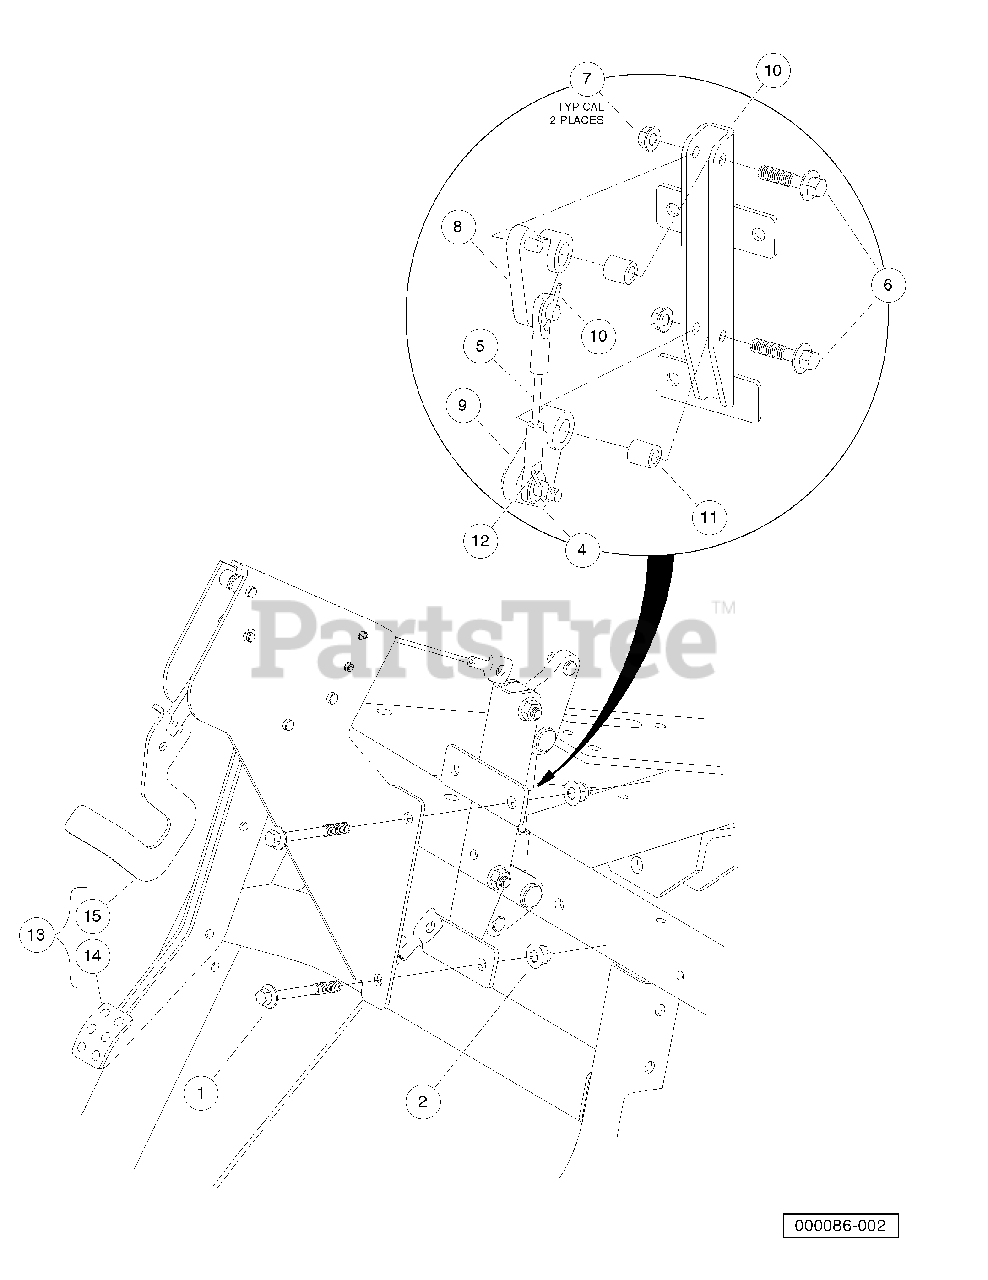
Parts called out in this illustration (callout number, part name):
1	Bolt Flanged Head, M8 X 1.25 X 65
2	Lock Nut, Flg M8 X 1.25 Nylon
3	Asm, Sub, Bracket, Park Brake
4	Washer, Flat, 3/8, Blk Fin
5	Cable, Crank, Bell
6	Bolt Flg, M8x1.25 X 35, Gr10.9
7	Nut Flg M8 X 1.25 Gr 10
8	Asm, Bellcrank, Upper
9	Asm, Bellcrank, Lower
10	Brkt, Bellcrank, Prk Brk, Awd
11	Spacer, Pivot, Park Brk, Awd
12	Pin, 3/32 X 1.00 Sq Cut Cotter
13	Asm, Pedal, Brake, Hard
14	Pedal, Brake, Park
15	Handle, Release, Park Brake
